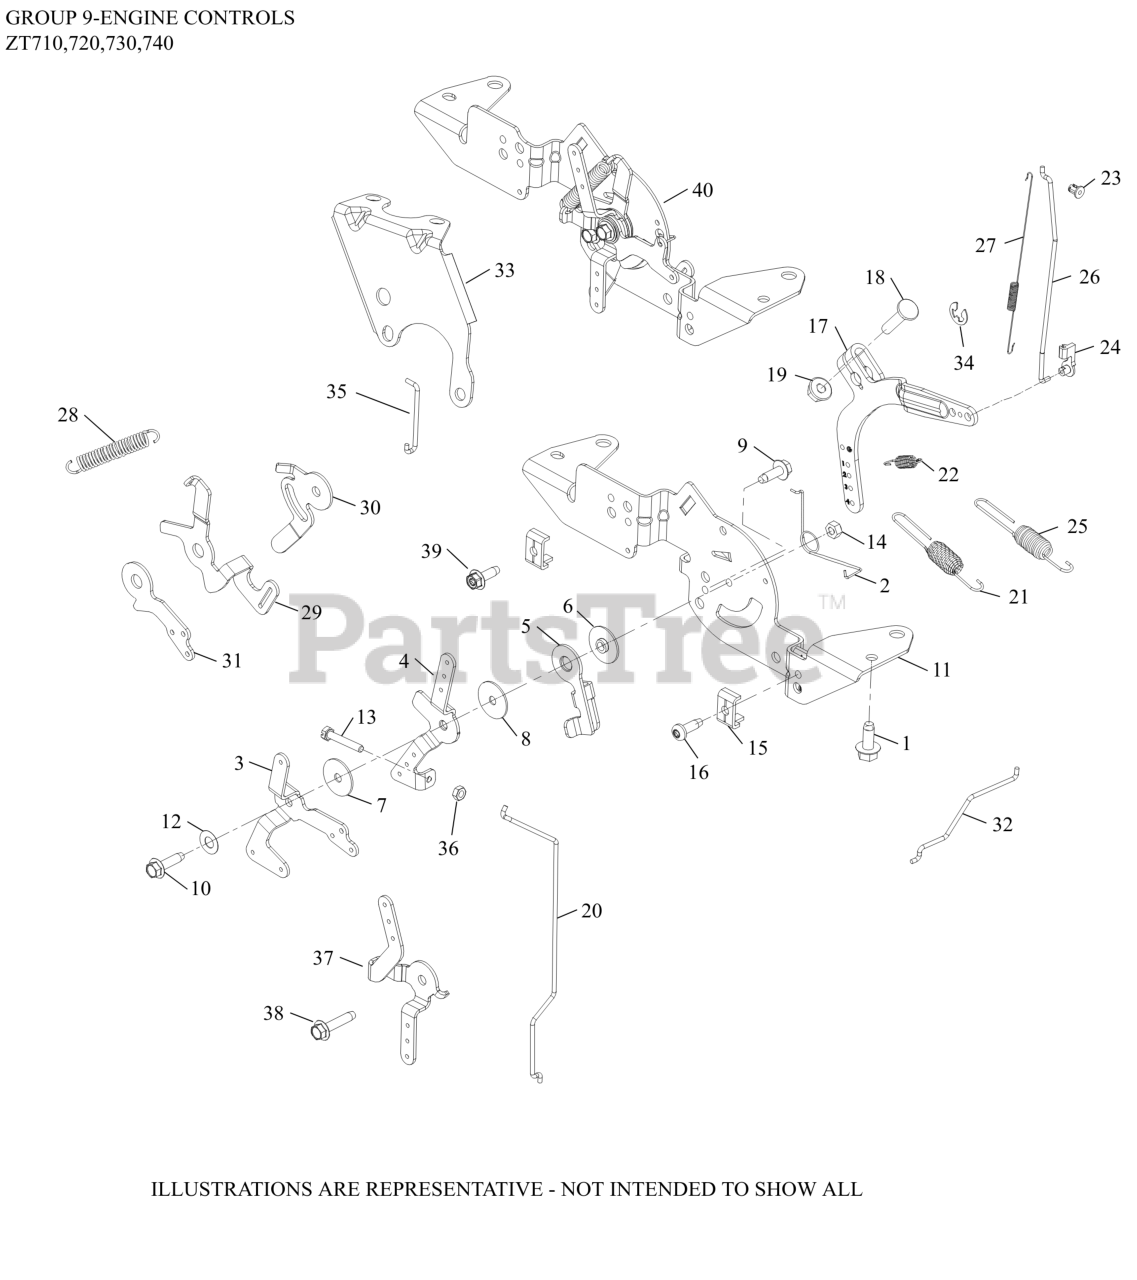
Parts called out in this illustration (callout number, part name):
1	SCREW, THREAD FORMING
2	SPRING, CHOKE RETURN
3	LEVER, CHOKE
4	LEVER, THROTTLE CONTROL
5	LEVER, THROTTLE ACTUATOR
6	SPACER, CONTROL ASSEMBLY
7	WASHER, FLAT 5.5 MM
8	WASHER, FLAT 5 MM
9	SCREW, THREAD FORMING
10	SCREW, THD FRM-USE 25 086 473-S
11	BRACKET, SPEED CONTROL
12	WASHER, SPRING 1/4"
13	SCREW, SLT HD CAP M4X0.7X25
14	NUT, LOCK M5X.8
15	CLAMP, CABLE-(#2523753S)
17	LEVER, GOVERNOR - (#2409069S)
18	BOLT, RD HD SQ NECK M6X1.0X25
19	NUT, FLG M6X1.0
20	LINKAGE, CHOKE
21	SPRING, GOVERNOR (ORANGE)
22	SPRING, GOVERNED IDLE
23	BUSHING, LINKAGE RETAINING
24	BUSHING, THROTTLE LINKAGE
27	SPRING, LINKAGE
32	LINKAGE, THROTTLE
34	CLIP, RETAINER GOVERNOR SHAFT
36	NUT, M4X0.7
37	SCREW, THREAD FORMING
